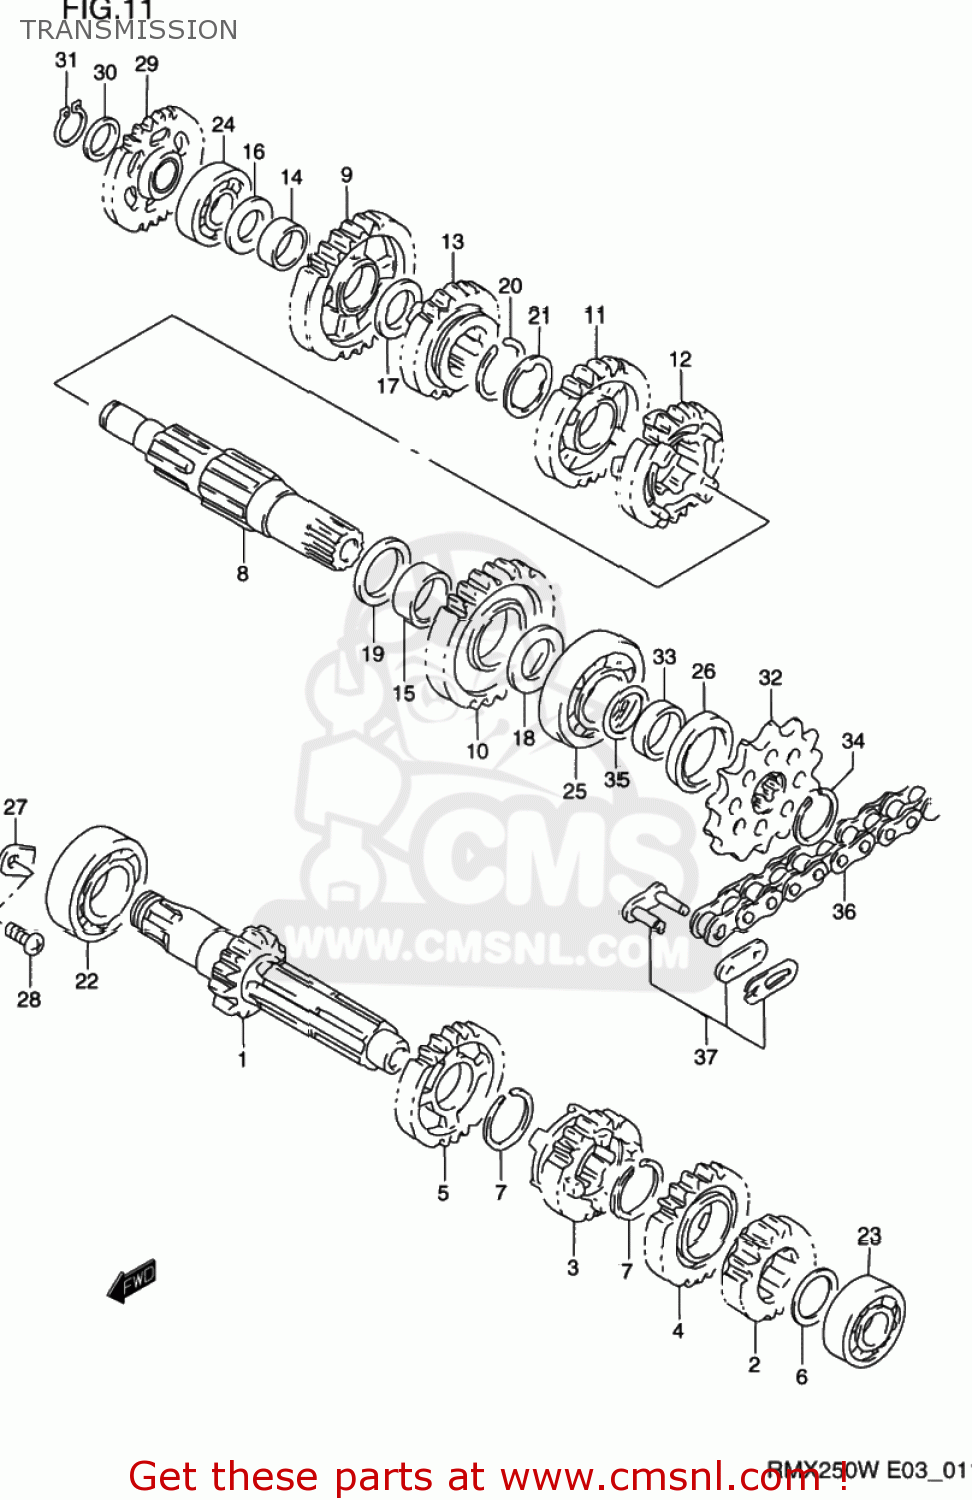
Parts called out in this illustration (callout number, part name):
1	SHAFT,COUNTER(NT:14)
2	GEAR,2ND DRIVE(NT:15)
3	GEAR,THIRD DRIVE (NT:16)
4	GEAR,FOURTH DRIVE (NT:22)
5	GEAR,5TH DRIVE(NT:22)
6	SHIM(17X30X1)
7	CIRCLIP
8	SHAFT,DRIVE
9	GEAR,1ST DRIVEN(NT:32)
10	GEAR,2ND DRIVEN(NT:26)
11	GEAR,3RD DRIVEN(NT:22)
12	GEAR,FOURTH DRIVEN (NT:24)
13	GEAR,5TH DRIVEN(NT:19)
14	BUSH(20X24X10)
15	BUSH(25X28X10)
16	SHIM(17X30X1)
17	SHIM(20X30X1)
18	SHIM (22X32X1.5)
19	SHIM(25X34X1)
20	CIRCLIP
21	WASHER,LOCK
22	BEARING(25X52X15)
23	BEARING(17X40X12)
24	BEARING(17X40X12)
25	BEARING(22X56X15)
26	SEAL,OIL(28X38X6)
27	RETAINER
28	SCREW
29	GEAR,KICK STARTER IDLE(NT:27)
30	SHIM(17X24X0.5)
31	CIRCLIP,17MM
32	SPROCKET(NT:15)
33	SPACER,ENGINE SPROCKET
34	CIRCLIP
35	O RING(D:1.9,ID:21.8)
36	CHAIN,DRIVE
37	JOINT,CHAIN
